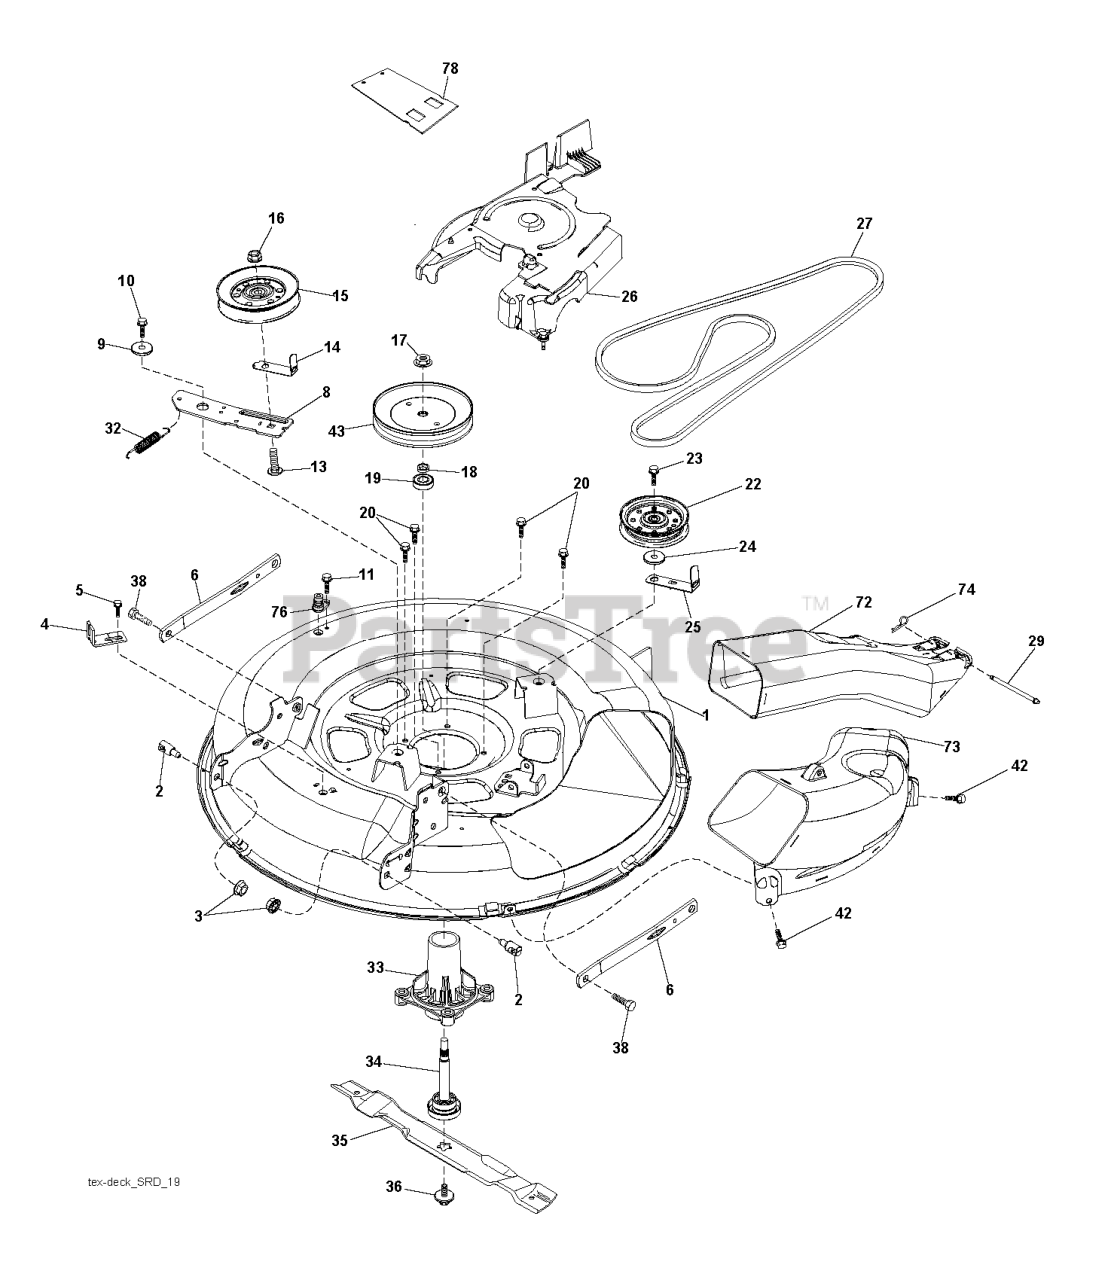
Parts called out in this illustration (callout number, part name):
1	DECK.WELDMENT.30"SRD.BLACK
2	STUD.FASTNER.W/ANTI-ROTATE
3	NUT LOCK HEX FLANGE 5/16-18
4	BRACKET.CLUTCH.CABLE
5	BOLT.5/16HEX.WHS.HD
6	ARMS.SUSP.MOWER.REAR.SRD
8	ARM.IDLER.30"SRD
9	SPACER.RETAINER
10	SCREW 3/8-16X1
11	SCREW.1/4-20X5/8
13	BOLT.3/8-16X1.50
14	KEEPER, BELT IDLER
15	PULLEY.IDLER.4.25
16	NUT LOCK FLG 3/8-16 UNC
17	NUT.FLANGE.LOCK.TOP
18	WASHER.SPACER.MANDREL
20	SCREW, WASHER HEAD
22	PULLEY.IDLER.FLAT.UNPLATED
23	SCREW LT
24	WASHER
25	KEEPER.BELT.30"SRD
27	V-BELT.DRIVE.MOWER.30"
29	PIN.HINGE.30".SRD
32	SPRING.MOWER.DRIVE.ELECTRIC
33	RP.HOUSING.MANDREL.4PT.
34	SHAFT.ASM.MDRL.N/GREASE.38
35	BLADE, MULCH.LRV30
36	BOLT.WASHER.ASM.7/16-2
38	BOLT.SHOULDER
42	SCREW, 3/8-16X3/4
43	PULLEY, MANDREL 6.5 PD
72	CHUTE.UPPER.SRD.30R"
73	CHUTE.LOWER.SRD.30R"
74	RETAINER-SPRNG RB
76	PORT.WASHOUT
78	GUARD ARM CLUTCH
